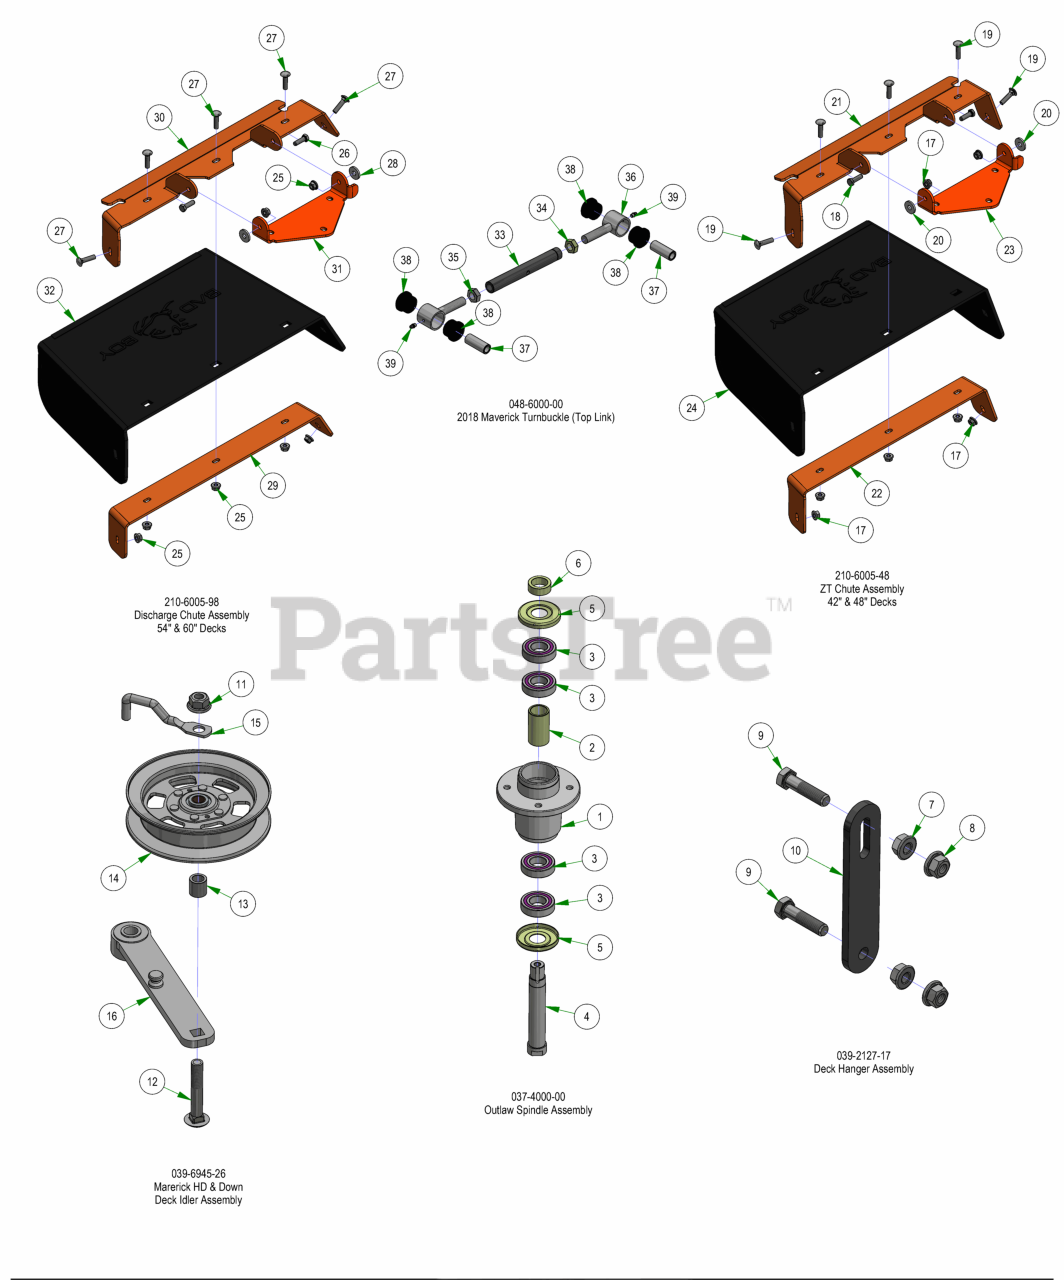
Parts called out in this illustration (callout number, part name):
1	4000 Series Spindle Housing
2	4000 Series Spindle Spacer
3	Bearing - 6206
4	Spindle Shaft
5	Spindle Dust Cap
6	Locking Collar w/ 1/4"-20 Set Screw
7	3/8-16 HEX SERRATED FLANGE NUT HARD/ZINC
8	3/8-16 NYLON INSERT FLANGE LOCKNUT (GR.F) ZINC
9	3/8-16 X 1-1/2 HEX CAP SCREW (GR.5) ZINC
10	2017 MZ/ZT Deck Hanger
11	1/2-13 NYLON INSERT FLANGE LOCKNUT ZINC
12	1/2-13 x 3 Carriage Bolt Grade 5
13	.51 ID X .75 OD X .75 LGTH SOLID SPACER ZINC
14	5" Idler Pully
15	2025 R-Series Belt Retainer
16	2025 Tensioner Arm With Bearings
17	5/16-18 NYLON INSERT FLANGE LOCKNUT ZINC
18	5/16-18 X 1 HEX CAP SCREW (GR.5) ZINC
19	5/16-18 X 1-1/4 CARRIAGE BOLT ZINC
20	.360 ID X .983 OD X .120 THICK FLAT WASHER NYLON
21	Discharge Upper Chute Bracket
22	Discharge Lower Chute Bracket
23	Discharge Chute Hanger (deck mounted)
24	Rubber Discharge Chute
25	5/16-18 NYLON INSERT FLANGE LOCKNUT ZINC
26	5/16-18 X 1 HEX CAP SCREW (GR.5) ZINC
27	5/16-18 X 1-1/4 CARRIAGE BOLT ZINC
28	.360 ID X .983 OD X .120 THICK FLAT WASHER NYLON
29	60" Discharge Lower Bracket
30	60" Discharge Chute Upper Hanger
31	Discharge Chute Hanger (deck mounted)
32	Rubber Discharge Chute
33	2018 Maverick Toplink Body
34	NUT, 5/8-18LH
35	NUT, 5/8-18
36	2018 Maverick Bushing Retainer Left-Handed
37	2018 Maverick Bushing Sleeve
38	2018 Maverick Bushing
39	1/4-28 Grease Fitting
